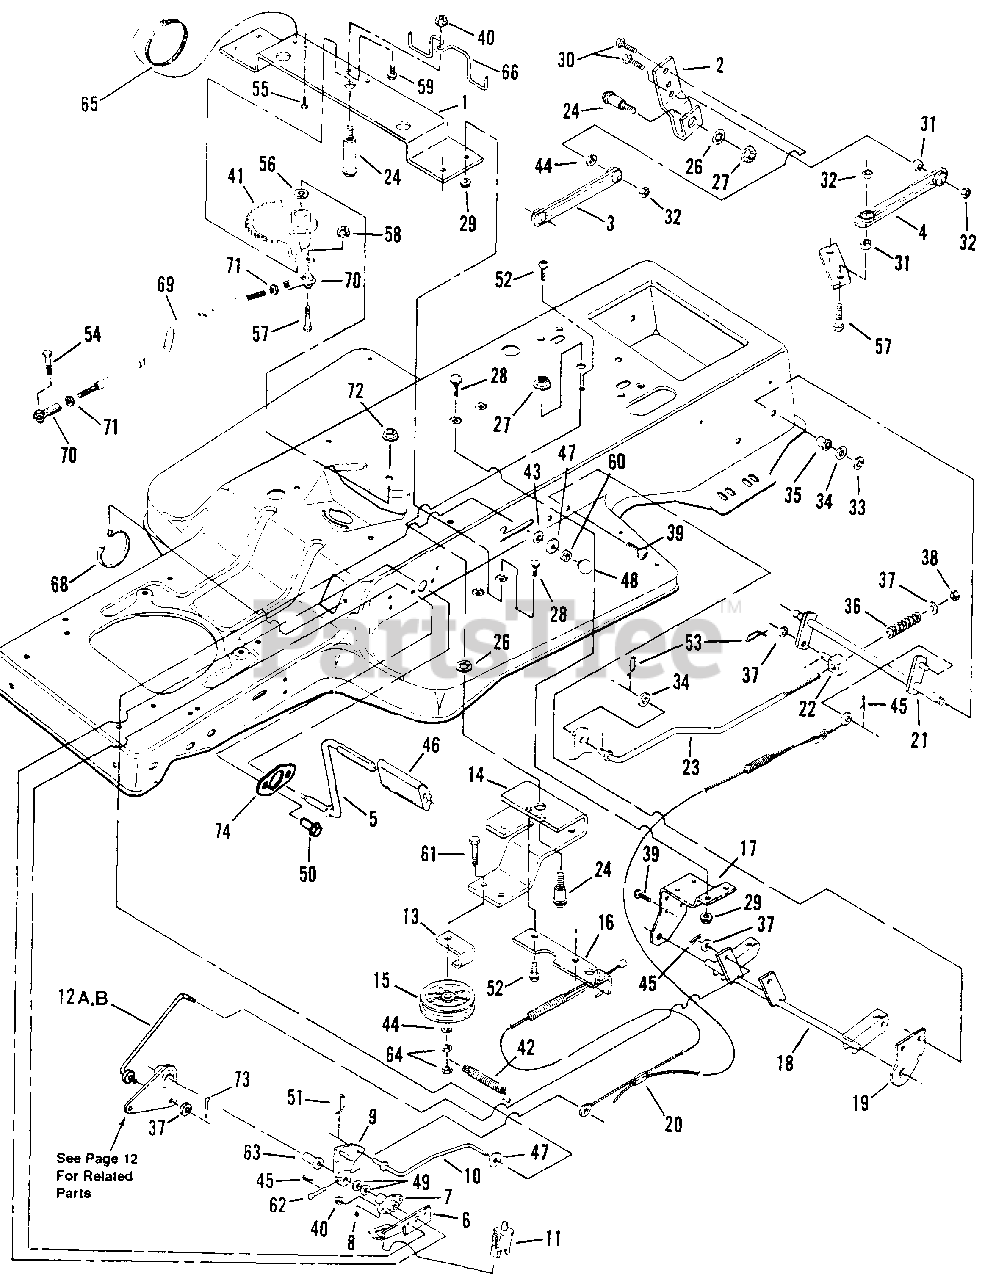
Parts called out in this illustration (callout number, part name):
1	BRACE, Sector Gear
2	BELLCRANK, Shift Lever
3	LINK, Shift Lever
4	LINK, Shift Lever (Twisted)
5	PEDAL, Park Brake
6	BRACKET, Brake Switch
7	ASSEMBLY, Foot Shaft Pivot
8	FITTING, 3/16 Lube
9	ASSEMBLY, Clutch/Brake Arm
10	LATCH, Park Brake
11	SWITCH
12A	ROD, Lift Link
12B	ROD, Lift Link
13	GUIDE, Pulley
14	ARM, Idler
15	PULLEY
16	EXTENSION, Idler Arm
17	BRACKET, Rear Lift/PTO Lever
18	WELDMENT, Rear Lift
19	BRACKET, Deck Hang Pivot
20	ASSEMBLY, Clutch/Brake Cable
21	WELDMENT, Brake Pivot
22	SWIVEL, Brake Link
23	ROD, Brake
24	BOLT, 1/2-13 x 2" Shoulder
25	BOLT, 1/2-13 x 3-7/8" Shoulder
26	WASHER, 1/2 Internal Lk.
27	NUT, 1/2-13 Hex Flange Lock
28	BOLT, 1/4-20 x 5/8" Carriage
29	NUT, 1/4-20 Flange Lock
30	SCREW, 3/8-16 x 1-1/4" Hex Head Cap
31	SPACER
32	NUT, 3/8-16 Center Lock
33	RING, 1/2" Ext. Retaining
34	WASHER, 1/2" Flat
35	BEARING, Nylon
36	SPRING, Brake
37	WASHER, 3/8" Flat
38	NUT, 3/8-16 Hex Top Nyloc
39	SCREW, 5/16-18 x 5/8" Truss Head
40	NUT, 5/16-18 Hex Flange Lock
41	ASSEMBLY, Sector Gear
42	SPRING
43	RETAINER, 5/16" Bolt
44	WASHER, 3/8 Split Lock
45	PIN, 3/32 x 1-1/2" Hair
46	PAD, Pedal
47	WASHER, 5/16 Nylon
48	KNOB, Push/Pull
49	WASHER, 5/8 Flat
50	SCREW, 5/16-18 x 7/8" Truss Head
51	PIN, 3/64 x 1-7/32" Cotter
52	SCREW, 5/16-18 x 5/8" Self-Tapping
53	COTTER-PIN, 1/16" x 1.42" Self-Locking
54	SCREW, 3/8-24 x 1-1/4" Hex Head Cap
55	SCREW, #10-24 x 1/2" Hex Washer Self-Tap (Torx)
56	WASHER, 3/4 Thrust
57	SCREW, 3/8-16 x 1-1/2" Hex Head Cap
58	NUT, 3/8-16 Hex Flange Lock
59	BOLT, 5/16-18 x 3/4" Hex Flange Lock
60	RING, Tolerance
61	SCREW, 3/8-16 x 2-1/4" Hex Head Cap
62	PIN, 3/16 x 1-1/2" Clevis
63	BEARING, Flange
64	NUT, 3/8-16 Hex Nut
65	TIE, Cable
66	GUIDE, Drive Belt
68	TIE, Wire
69	LINK, Drag
70	BALL JOINT, 3/8-24
71	NUT, 3/8-24 Hex Jam
72	NUT, 1/2-13 Hex Center Lock
73	PIN, 3/32 x 3/4" Cotter
74	WASHER, Pivot- Stiffener
